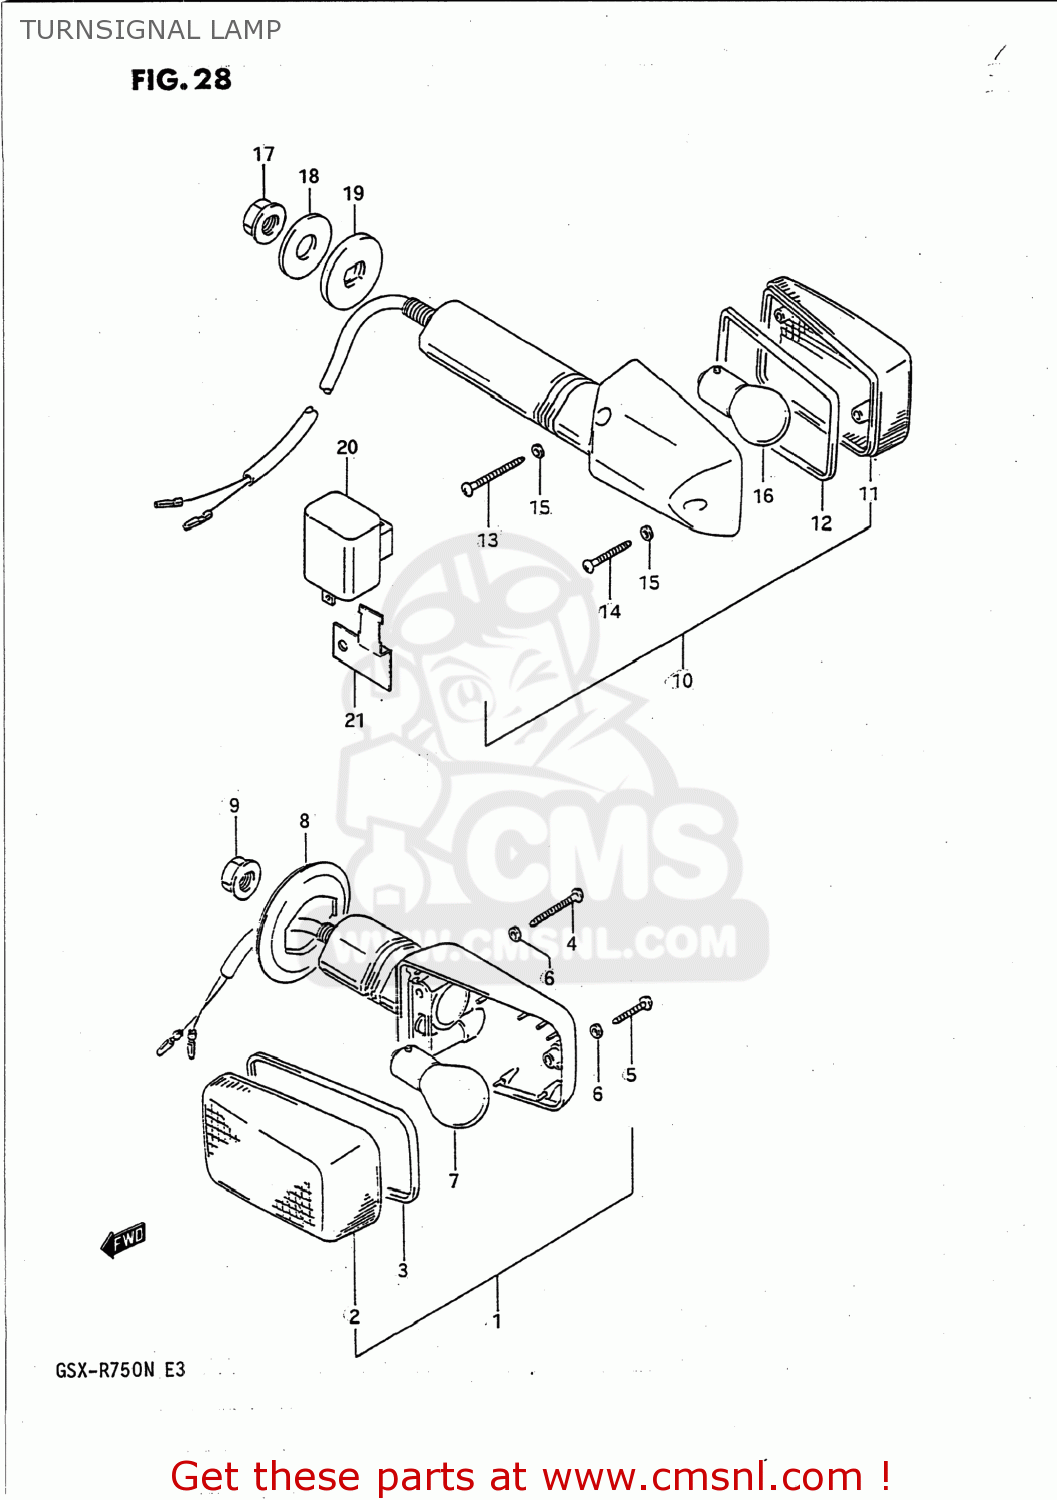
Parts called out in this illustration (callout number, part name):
1	LAMP ASSY,FR TURN SIGNAL
2	LENS
3	GASKET (NAS)
4	SCREW(3X30)
5	SCREW
6	GASKET (NAS)
7	BULB(12V21W)
8	GROMMET
9	NUT
10	LAMP ASSY,FR TURN SIGNAL
11	LENS
12	GASKET (NAS)
13	SCREW(3X30)
14	SCREW
15	GASKET (NAS)
16	BULB(12V21W)
17	NUT
18	WASHER(10.5X30X3.2)
19	SPACER,RR TURNSIGNAL
20	RELAY ASSEMBLY,TURN SIGNAL
21	BRACKET,TURN SIGNAL RELAY
